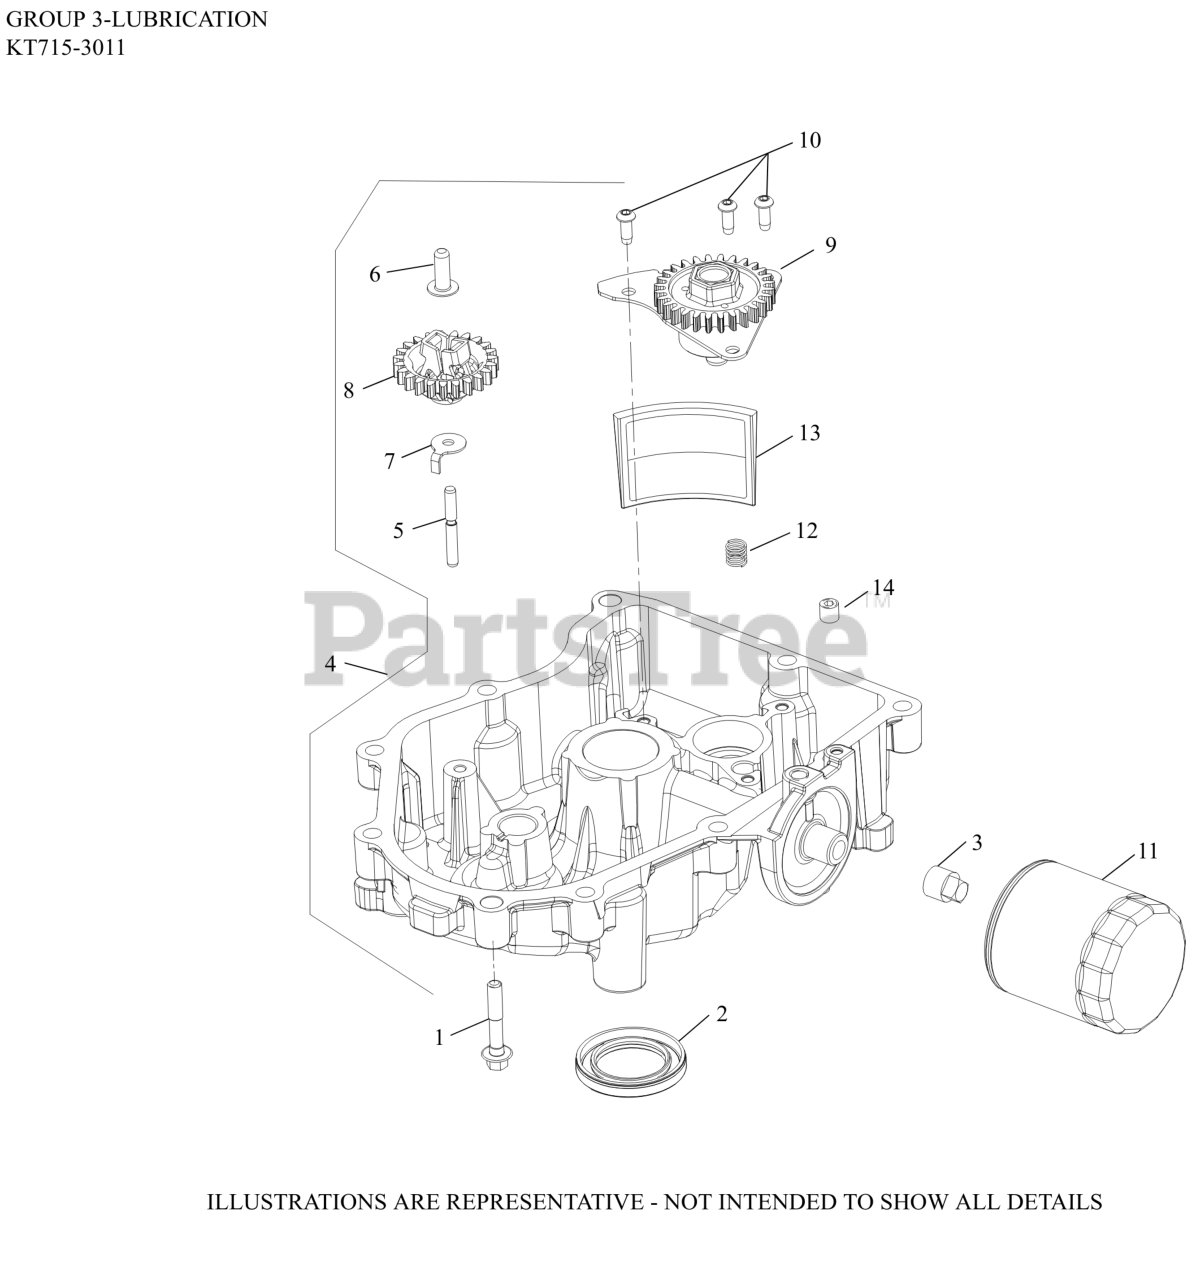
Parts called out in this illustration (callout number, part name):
1	SCREW, FLG M8X1.25X45
3	PLUG, SQ HD PIPE 3/8"
4	PAN ASSEMBLY, OIL-(#3219924S)
5	SHAFT, GOVERNOR GEAR
6	PIN, GOVERNOR REGULATING
7	TAB, LOCKING
8	KIT, GOVERNOR GEAR
9	PUMP ASSEMBLY, OIL
10	SCREW, BUTTON HEAD
11	OIL FILTER
12	SPRING, COMPRESSION
13	SCREEN, OIL
14	PLUG, CTSK PIPE 1/8"
